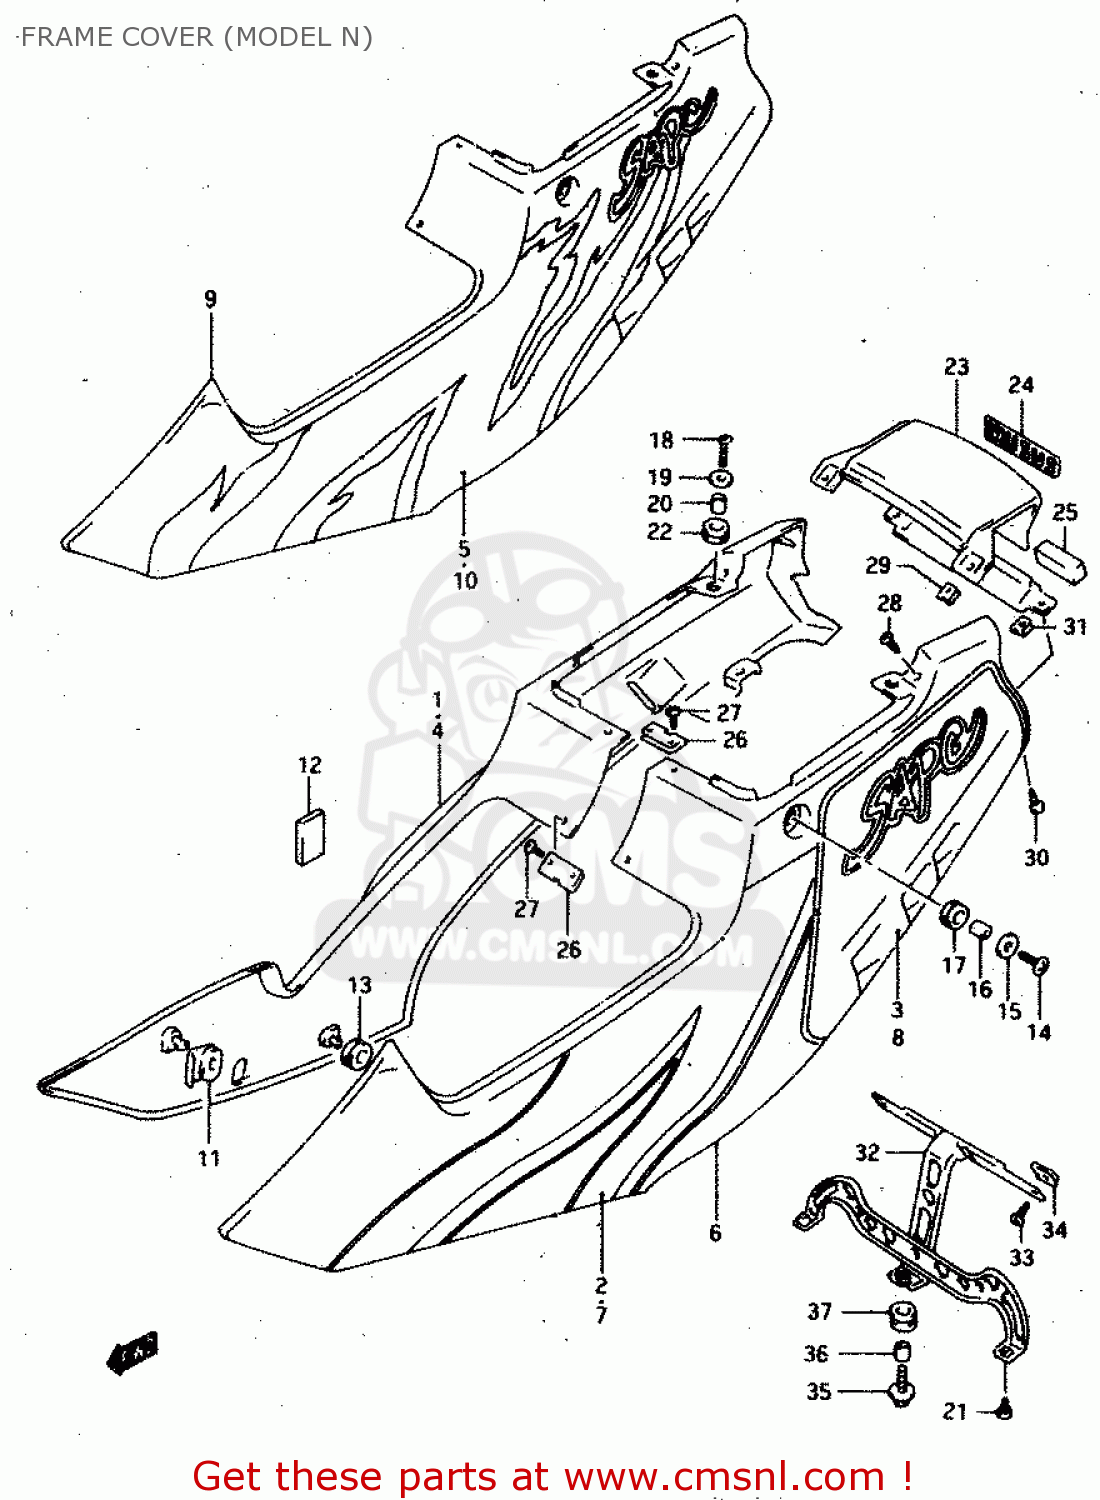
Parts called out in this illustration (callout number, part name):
1	COVER, FRAME RH (WHITE)
2	TAPE, FRAME COVER RH
3	TAPE,FRM,ZECKE
4	COVER, FRAME RH (BLACK)
5	TAPE, FRAME COVER RH1
6	COVER, FRAME LH (WHITE)
7	TAPE, FRAME COVER LH
8	TAPE, STICKER
9	COVER, FRAME LH (BLACK)
10	TAPE, FRAME COVER LH
11	CUSHION,FRAME COVER FR
12	TAPE,FRAME PROTECTOR
13	CUSHION
14	SCREW(6X20)
15	WASHER(6.5X22X1.6)
16	SPACER (6.3X9.1X6.7)
17	CUSHION
18	SCREW, CENTER
19	WASHER (6.5X20X1.6)
20	SPACER (6.3X9.1X6.7)
21	SCREW (6X16)
22	CUSHION
23	COVER, FRAME CENTER (WHITE)
24	EMBLEM
25	RUBBER
26	NUT,FRAME COVER CTR
27	SCREW
28	SCREW, BRACKET
29	NUT
30	SCREW
31	NUT
32	BRACKET, TAIL LAMP REAR
33	SCREW
34	NUT
35	BOLT(6X20)
36	SPACER (6.1X8X9.5)
37	CUSHION
